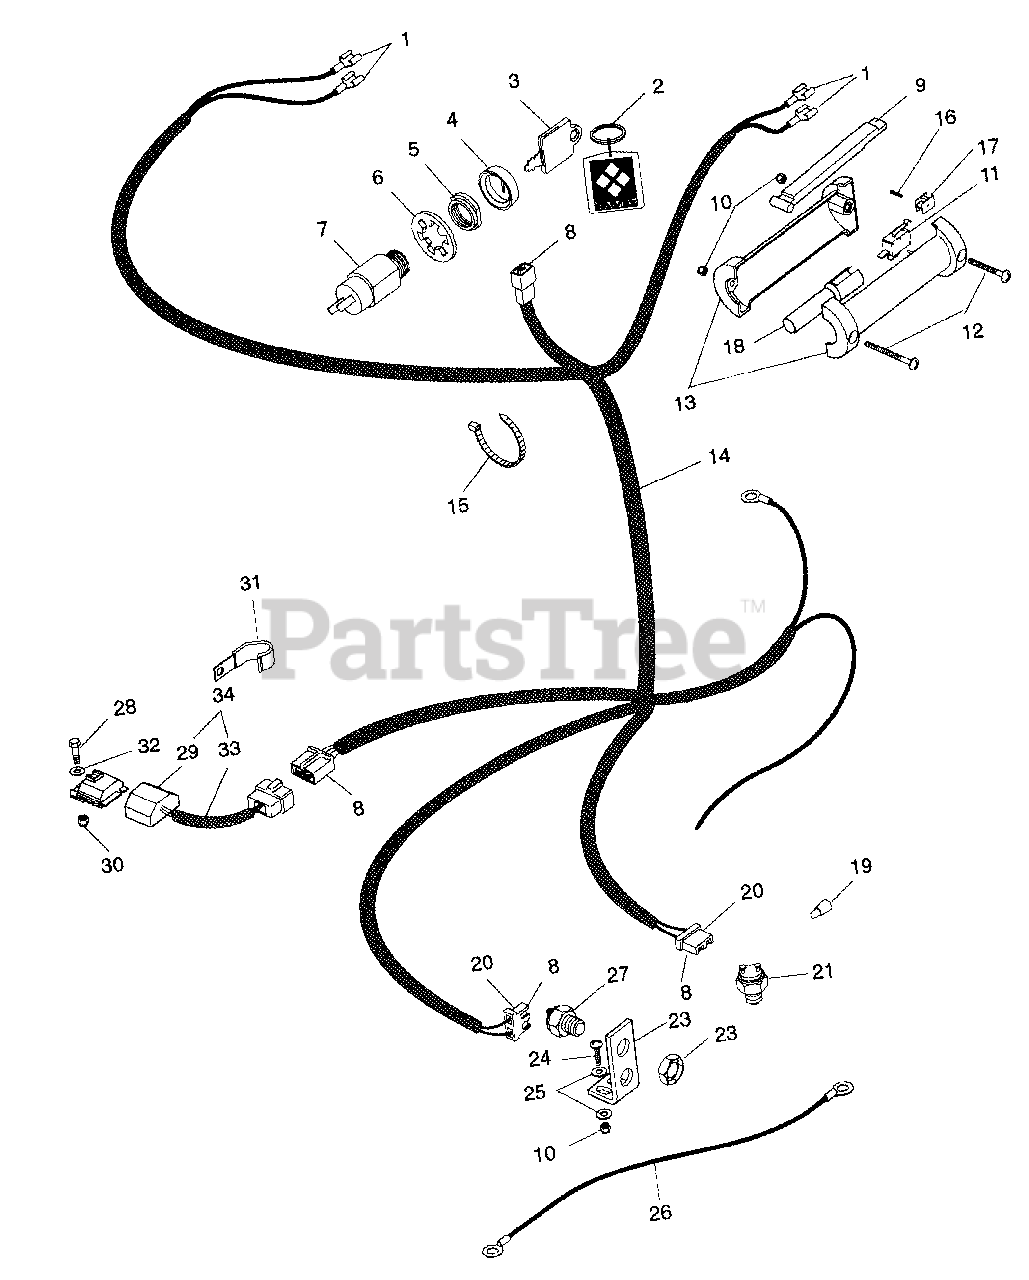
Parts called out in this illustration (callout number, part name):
1	Terminal, Female
2	Key Chain
3	Ignition Switch Key
4	Cap-Ignition Switch
5	Nut-Panel .625-32
6	Washer-Lock .625
7	Key Switch Assembly
8	Terminal
9	Lever
10	Nut-Locking 10-24
11	Switch
12	Screw-Maching 10-24 x 1.50
13	Handle, Left Hand & Right Hand
14	Harness, Wiring Pro Recoil
15	Tie Wrap, Black
16	Pin-Roll .094 x .750
17	Holder, Switch
18	Insert, Handlebar
19	Nut-Connector
20	Connector, 2-Wire Switch
21	Switch-Neutral Start
22	Bracket, Interlock Switch
23	Nut-Stamped .56-18
24	Bolt-Hex 10-24 x .75 Grade 2
25	Washer-Flat-Steel .188 x .438 x .049
26	Wire, Ground
27	Switch-Neutral Start
28	Bolt-Hex .25-20 x .75 Grade 5
29	Module
30	Nut-Locking-Nylon .250-20 Grade 2
31	J-Clamp
32	Washer-Flat-Steel .344 x .688 x .065
33	Adapter Harness
34	Kit, Interlock Module
